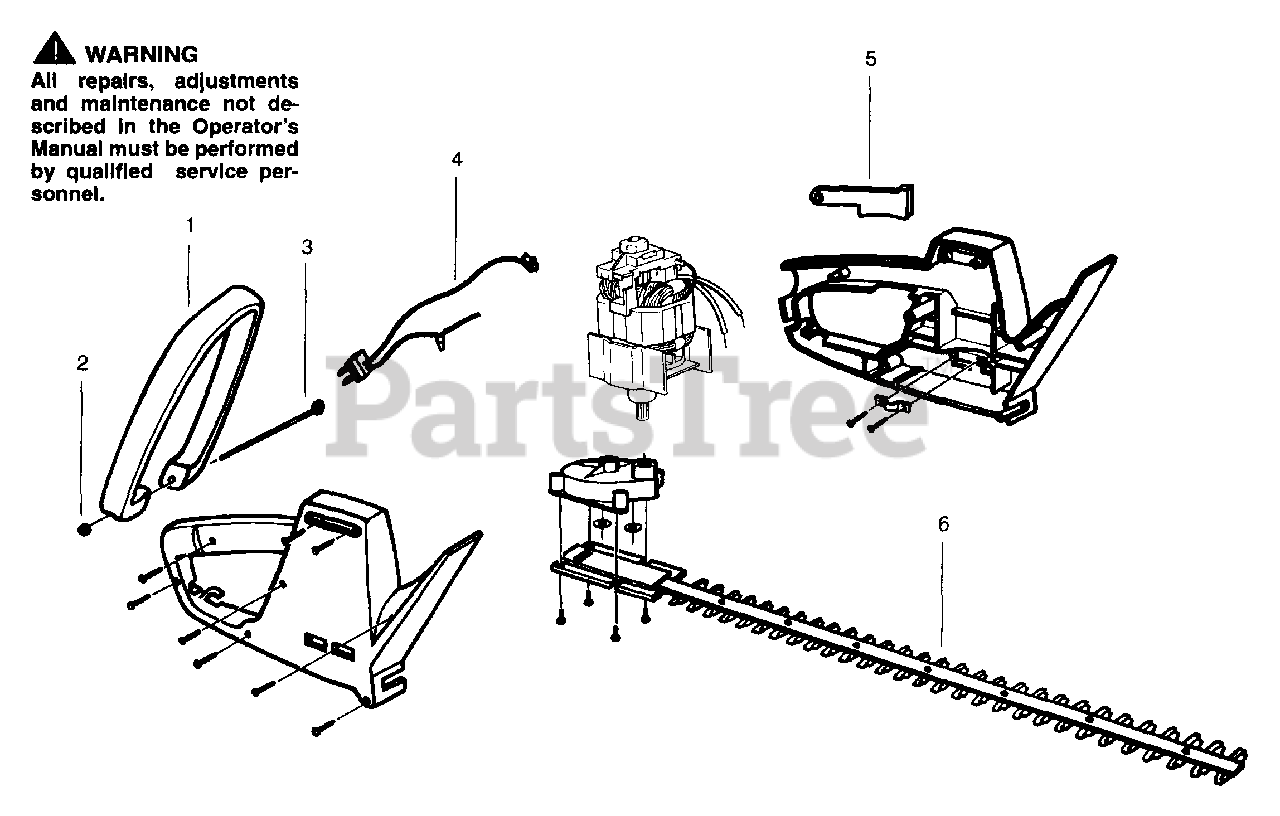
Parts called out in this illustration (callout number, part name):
1	Assist Handle
4	Wire Harness
6	Blade Ass'y - 14"
6	Blade Ass'y - 17"
6	Blade Ass'y - 20"
